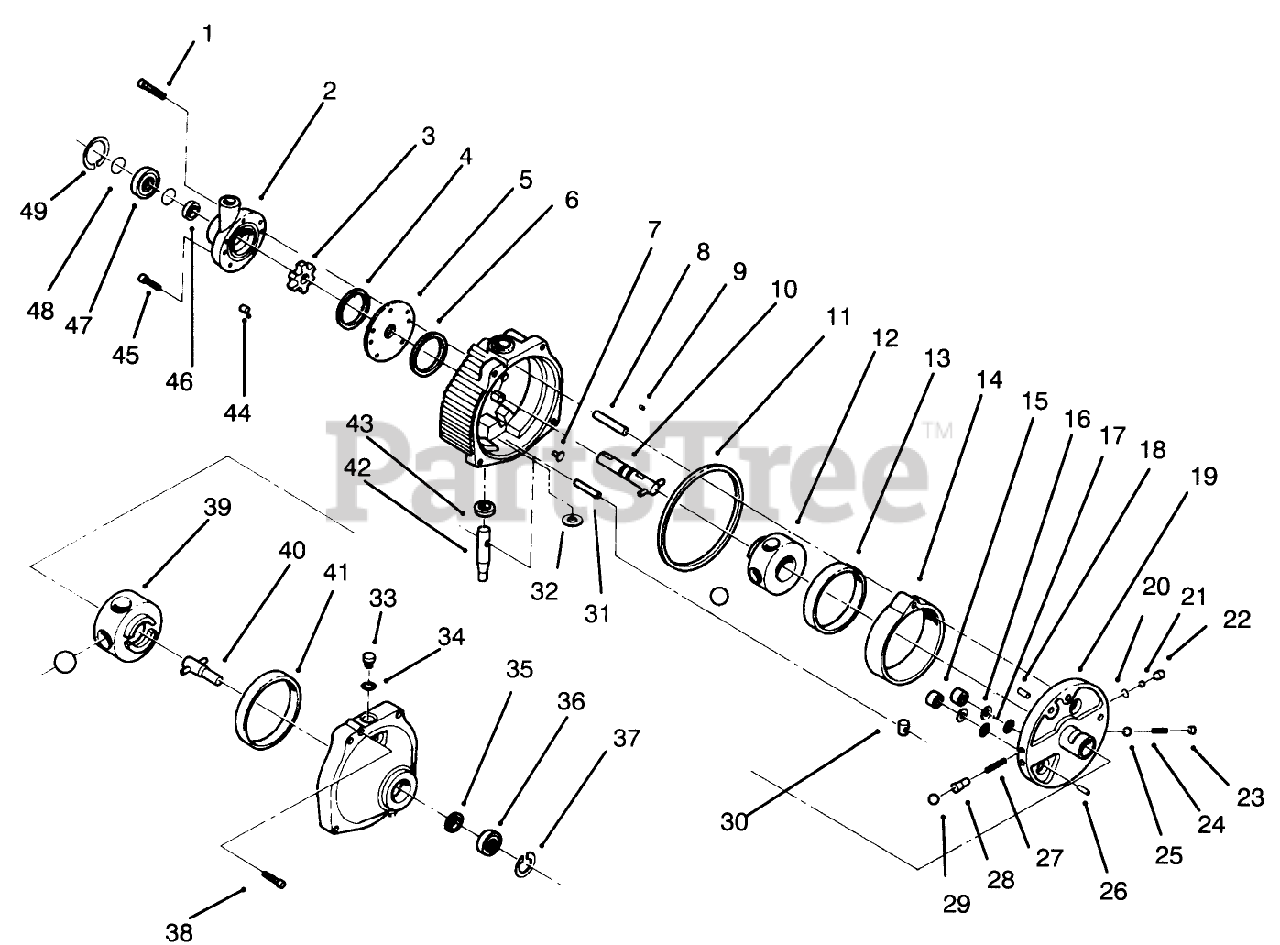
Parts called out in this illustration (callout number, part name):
1	CAPSCREW
2	Charge Pump Assembly (Incl. Ref. #1)
3	CARRIER
5	PLATE
7	BUTTON
8	Pin-Dowel
10	SHAFT
12	ROTOR
13	Race-Pump
14	Cam Ring Assembly (Incl. Ref. #13)
15	PISTON
17	O-RING
19	Pintle Assembly (Incl. Ref. #15-18, 20, 22-26 & 27-29)
24	SPRING
27	SPRING
30	INSERT
31	Dowel
32	Washer-Control Shaft
33	Plug Assembly (Incl. Ref. #34)
34	O-RING
35	Oil Seal
36	Bearing
38	Socket Head Capscrew
39	ROTOR
40	SHAFT
42	Control Shaft Kit (Incl. Ref. #31 & 32)
43	SEAL-OIL
45	SCREW-HH
46	SEAL-OIL
47	BEARING
49	RING
